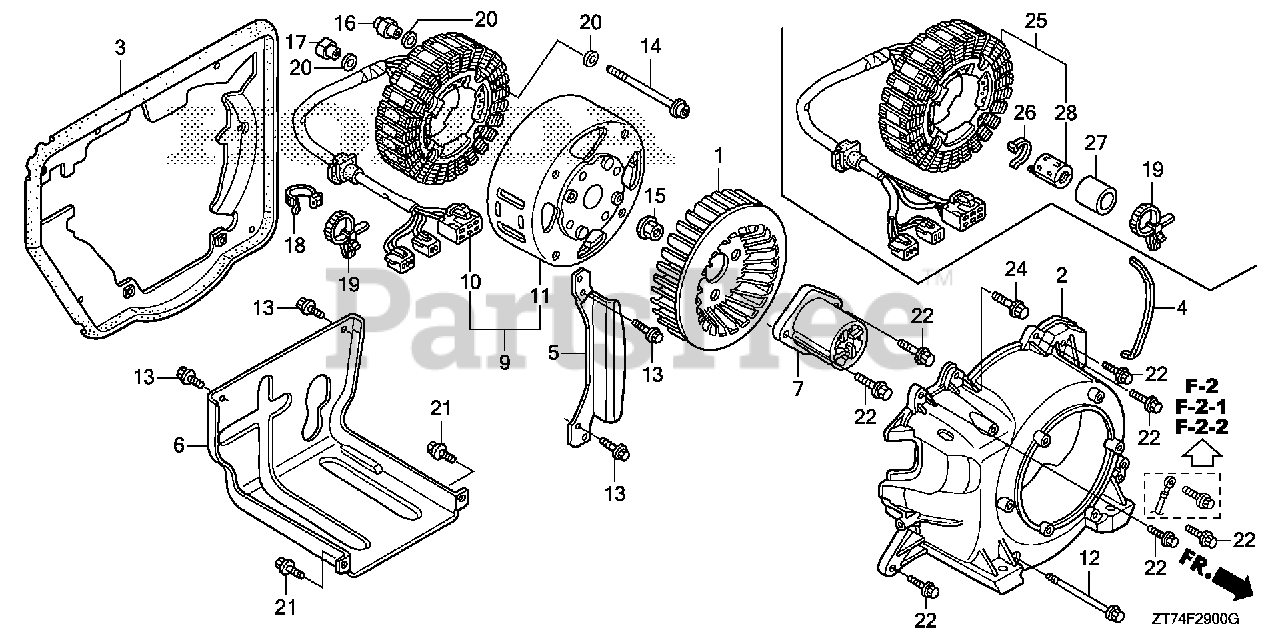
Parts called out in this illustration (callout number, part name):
1	FAN, COOLING
2	COVER, FAN
3	SEAL, FAN COVER
4	SEAL, FAN COVER
5	BRACKET, FAN COVER
6	SHROUD (LOWER)
7	PULLEY, STARTER STARTER MOTOR & RECOIL
9	GENERATOR ASSY.
10	STATOR ASSY.
12	BOLT, FLANGE (6X112) (CT200)
13	BOLT, FLANGE (6X12) (CT200)
14	BOLT, FLANGE SOCKET (6X61) (CT200)
15	NUT, SPECIAL (14MM)
16	COLLAR, STATOR
17	COLLAR, STATOR
18	BAND, WIRE (95MM)
19	STRAP, CABLE (118MM) (BLACK)
21	BOLT, FLANGE (6X10)
22	BOLT, FLANGE (6X20)
24	BOLT, FLANGE (6X20) (CT200)
